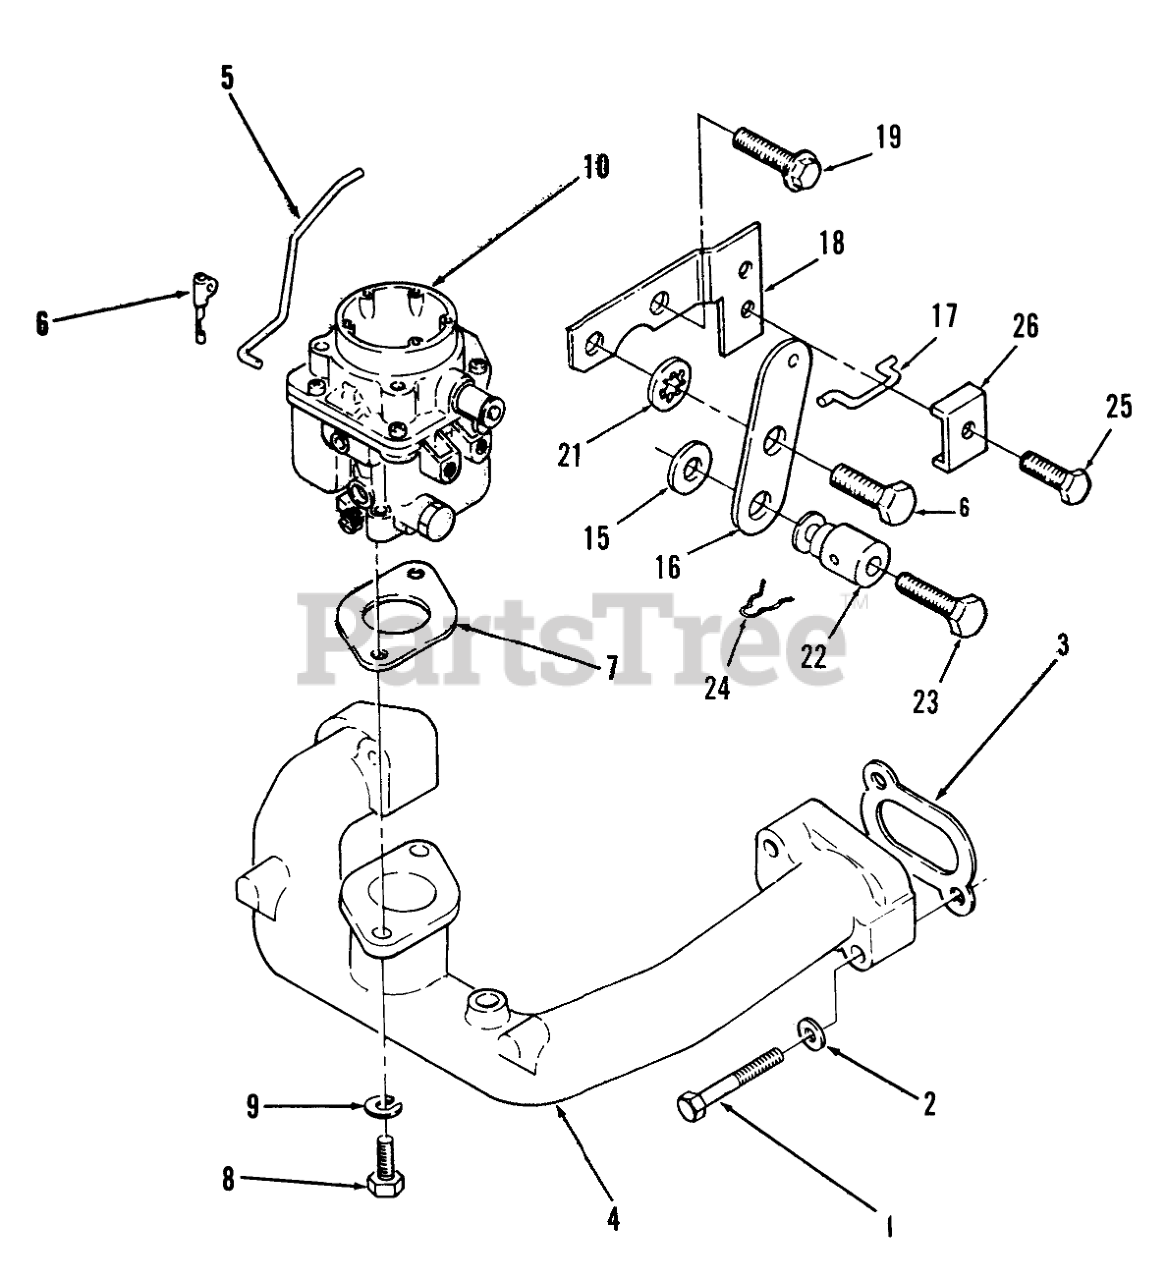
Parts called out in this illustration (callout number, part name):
2	Nut-M8
3	Gasket
4	INTAKE-MANIFOLD
5	GOVERNOR-CONTROL ROD
6	CONTROL-ROD CLIP
7	Gasket
8	HEX-HEAD CAP SCREW
9	Washer
10	COMPLETE-CARBURETOR
11	Hose 7 3/8"
12	Clamp
13	Filter-Fuel
14	Hose
15	Washer
16	Lever
17	Link
18	Bracket
19	Bolt
20	Bolt
21	Lockwasher
22	Swivel
23	Bolt
24	Cotler Pin
25	Bolt
26	Clamp
